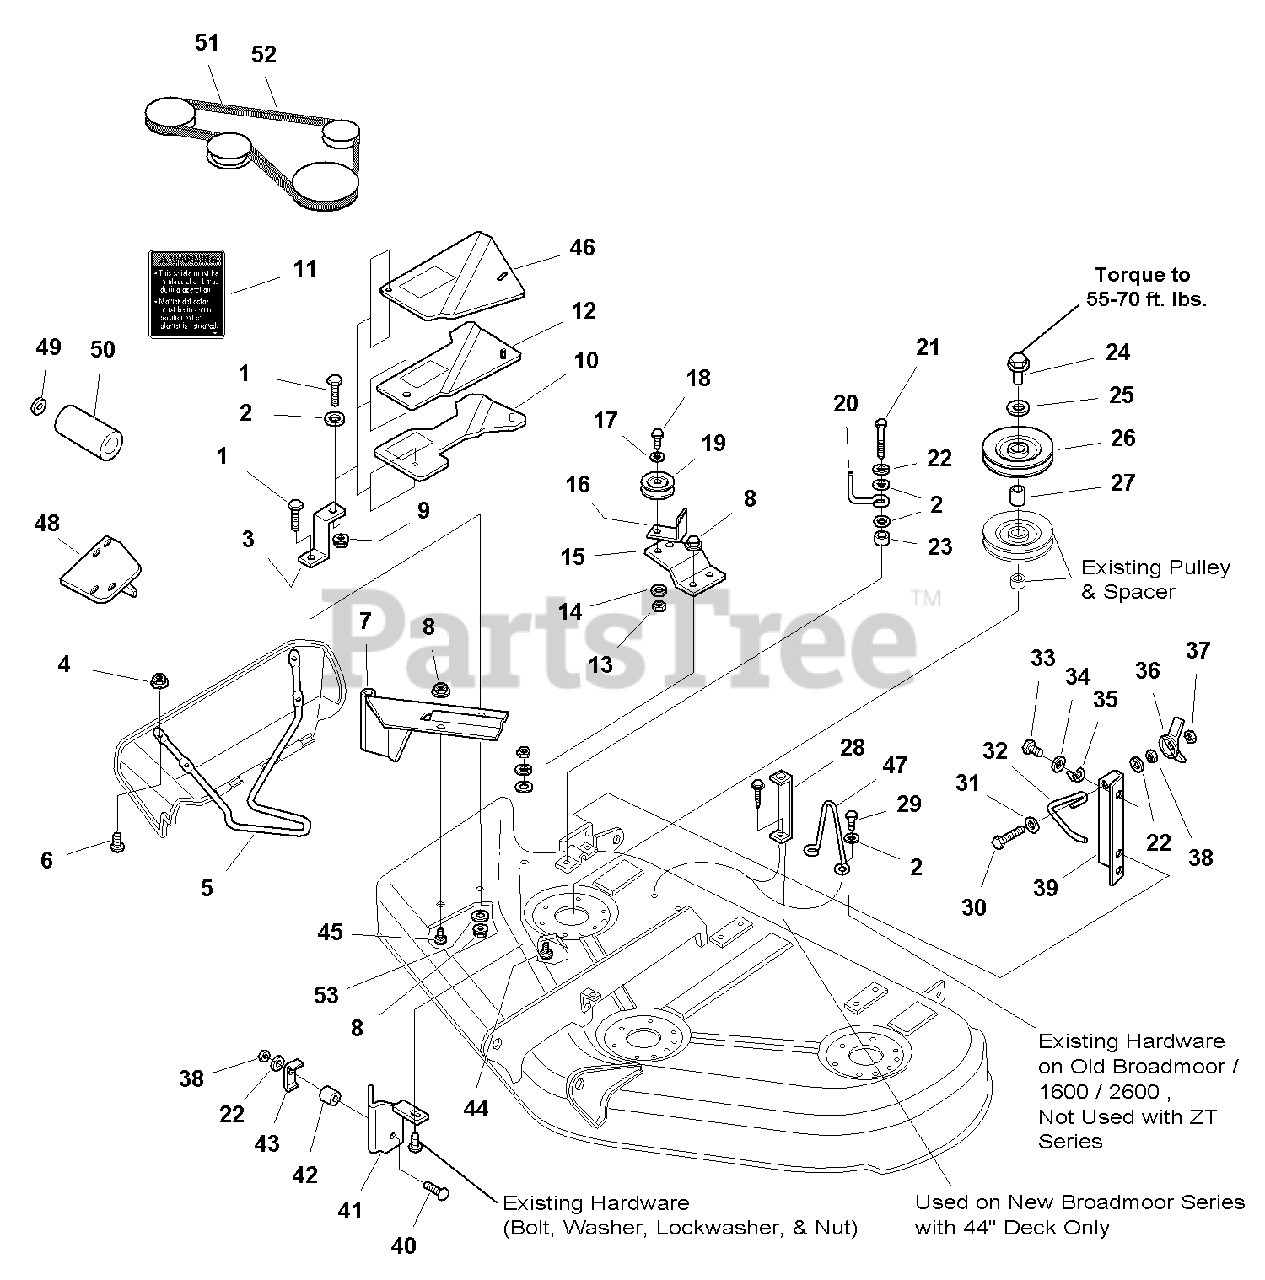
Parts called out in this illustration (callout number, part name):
1	CAPSCREW, Hex Head, 5/16-18 x 1
2	WASHER, 5/16
3	SUPPORT, Belt Cover
4	NUT, Hex, Nylon Lock, #10-24
5	ROD, Deflector
6	CAPSCREW, Truss Head, #10-24 x 3/4
7	PIVOT ASSEMBLY
8	NUT, Hex Whizlock, 5/16-18
9	NUT, Nylock, Hex, 5/16-18
10	COVER, Belt, 44" New Broadmoor Only
11	DECAL, Warning
12	COVER, Belt, 50" Conquest/Prestige 44" Old Broadmoor
13	NUT, Hex, 3/8-16
14	LOCKWASHER, 3/8
15	BRACKET, Idler
16	LATCH, Belt Cover
17	WASHER, Flat, 3/8
18	CAPSCREW, Hex Head, 3/8-16 x 1-1/2
19	PULLEY ASSEMBLY, Idler
21	CAPSCREW, Hex Head, 5/16-18 x 1-1/2
24	NUT, Sleeve
25	WASHER, Belleville
27	HUB, Double Pulley, 1.16" Long
28	UPSTOP, 5", Flat-Stock
29	CAPSCREW, Hex Washer Head, Taptite, 5/16
31	WASHER, 5/16
32	LATCH, Spring
33	CAPSCREW, Hex Head, 1/4-20 x 1/2
34	WASHER, 1/4
35	BELT STOP, (Height Indicator)
39	BRACKET, Anchor
40	CARRIAGE BOLT, 5/16-18
41	BRACKET ASSEMBLY, Cutoff
44	CAPSCREW, Hex Head, 5/16-18 x 7/8
45	CARRIAGE BOLT, 5/16-18 x 3/4
46	COVER, Belt, 50" Old Broadmoor/Landlord/ZT
47	UPSTOP,Wire
48	BRACKET, Mounting
49	PUSHNUT
51	V-BELT, 44" Turbo
52	V-BELT, 50" Turbo
53	WASHER, 3/8
